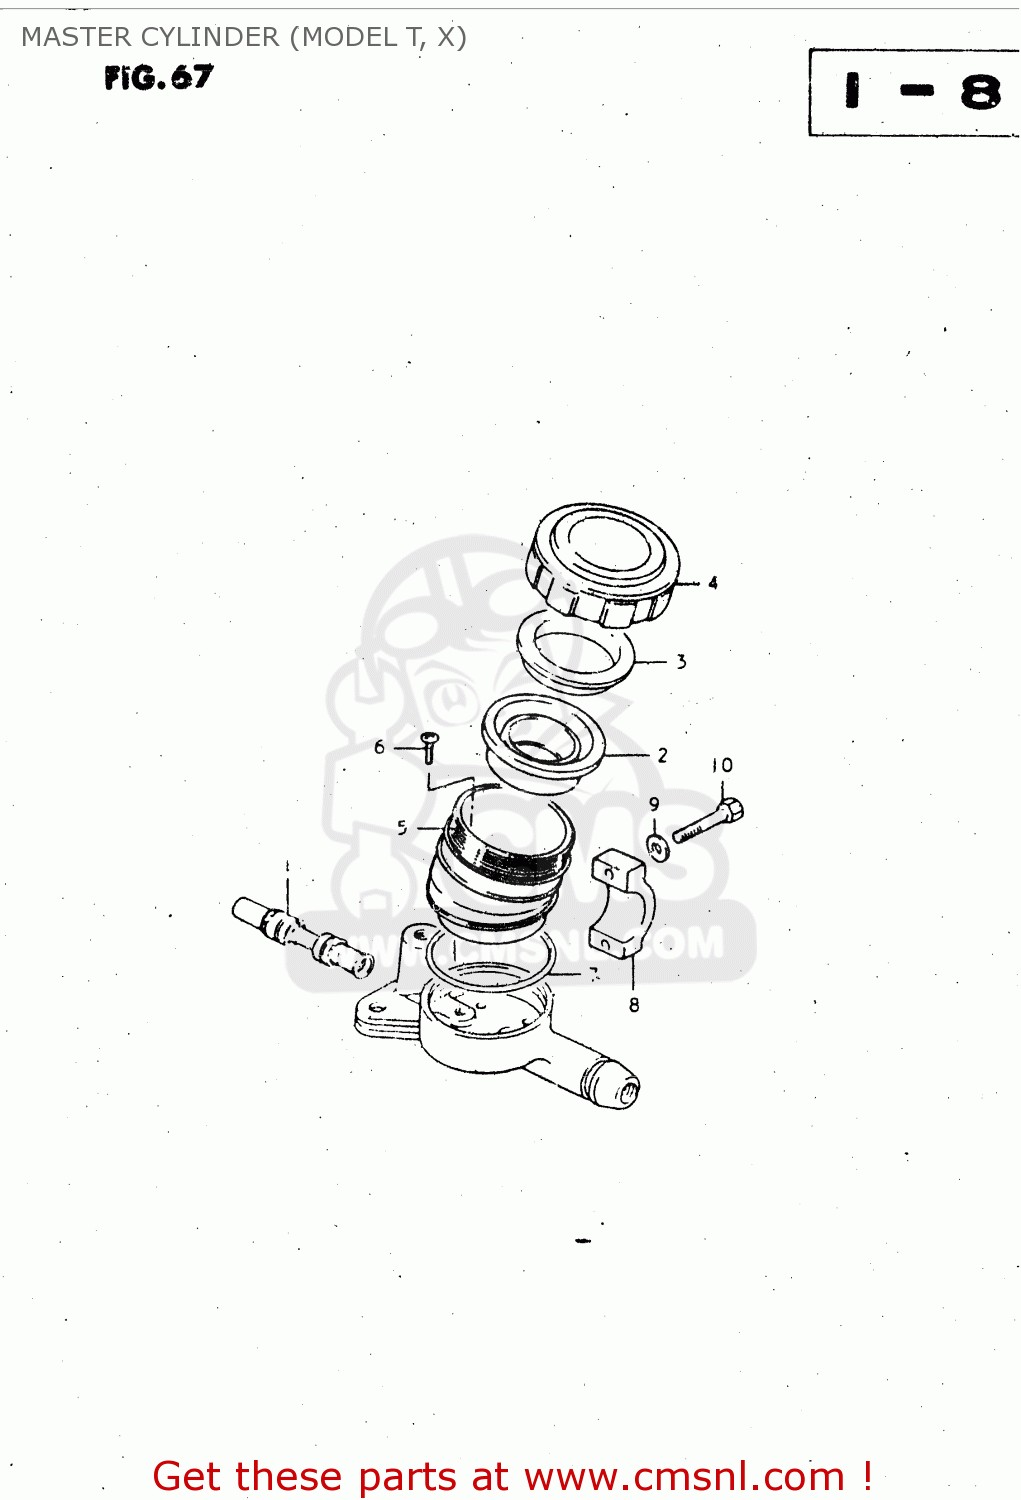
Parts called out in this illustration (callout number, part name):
1	PISTON & CUP SET
2	DIAPHRAGM
3	PLATE,DIAPHRAGM
4	CAP
5	RESERVOIR
6	SCREW,MASTER CYLINDER
7	O RING
8	HOLDER,MASTER CYLINDER
9	WASHER
10	BOLT
